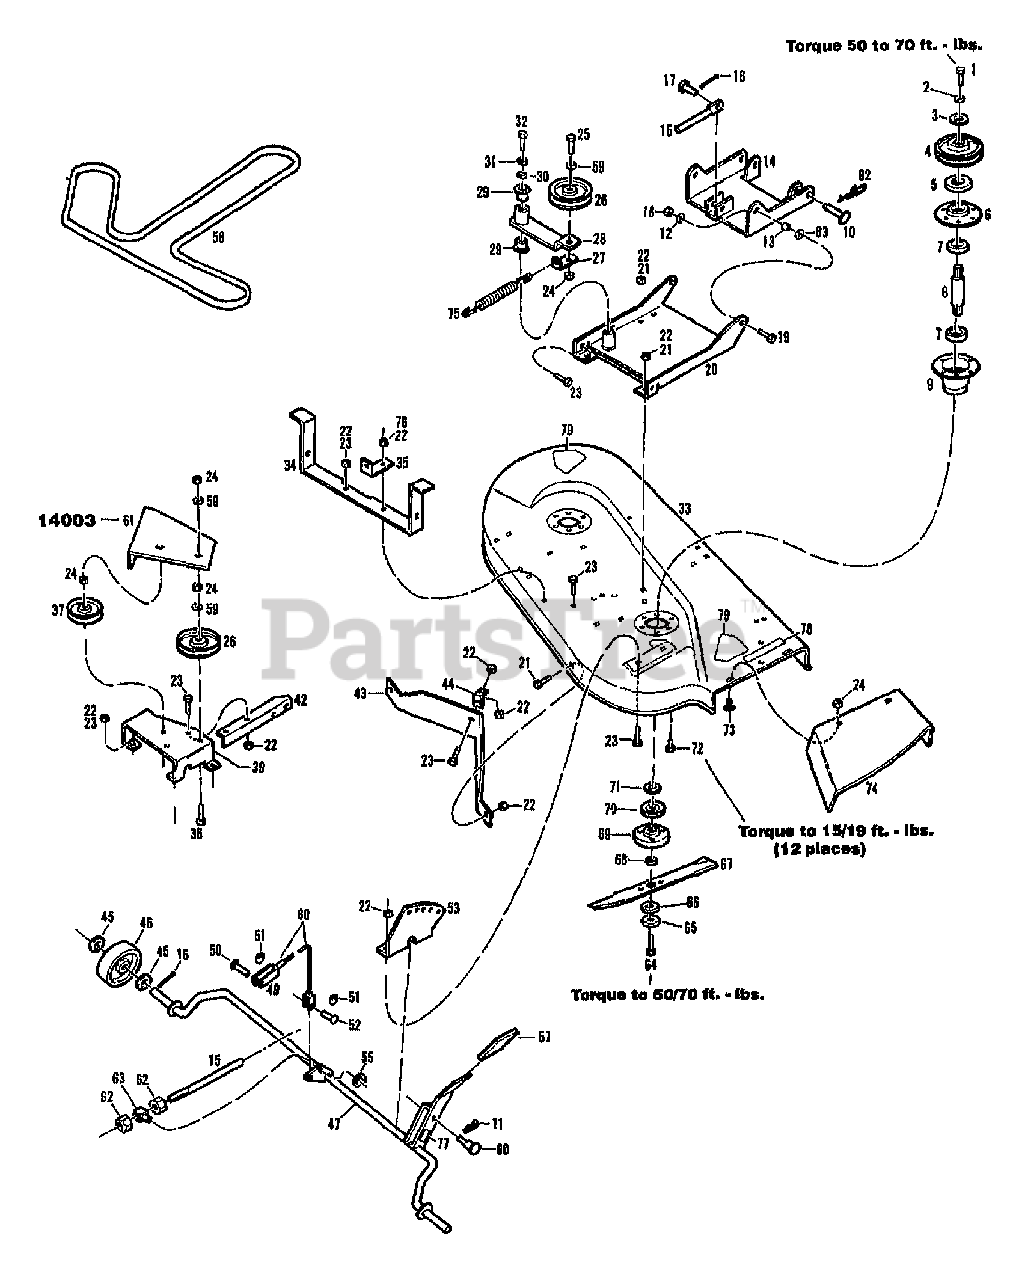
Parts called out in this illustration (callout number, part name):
1	SCR-HH 7/16-14X2.75 G5ZP
1	SCR-HH 7/16-14X3.0 G5 ZP
2	WASHER-LK .438 ZP
3	WASHER-1.37X.453X.179 ZP
4	ASSM-DRIVE SHEAVE
5	BEARING-UPPER SHIELD
6	HOUSING-ARBOR TOP
7	BEARING-BALL
8	SHAFT-ARBOR
9	HOUSING-ARBOR BOTTOM
10	PIN-CLEVIS .62X2.50 ZP
11	PIN-HITCH .125X2.56 ZP
12	WASHER-1/2 FLAT
13	SPACER-TUBULAR
14	ASSM-MOWER SUPT
15	ROD-ADJUSTOR
16	PIN-COTTER .120X1.25 ZP
17	PIN-CLEVIS .5X1.75 ZP
18	NUT-TOP LOCK 1/2-13 ZP
19	SCR-HH 1/2-13X1.25 G5 ZP
20	PLATE-MOWER SUPPORT
21	SCR-CARR 5/16-18X.75
22	NUT-TOP/LK 5/16-18 ZP
23	SCR-HHC 5/16-18X.75 GR 5 ZP
24	NUT-LOCK 3/8-16
25	SCR-HH 3/8-16X2.0 G5 ZP
27	GUIDE-BELT
28	ASSM-IDLER ARM
29	BEARING-FLANGE
30	WASHER-FLAT
31	WASHER-LK .375 @ DEPL
32	SCR-HH 3/8-16X.75 G5 ZP
33	ASSM-36" DECK W/DECALS
35	SPRING-ANCHOR
36	SCR-HH 3/8-16X2.25 G5 ZP
37	PULLEY-IDLER
39	SUPT-IDLER/AXLE
42	BRKT-SUPPORT
44	BRACKET-MOWER
45	WASHER-1.38 X.765X .06 ZP
46	GAUGE-WHEEL
47	ASSM-SUPT WHEEL SHAFT
49	YOKE
50	PIN-CLEVIS .5X1.437 ZP
51	RING-CIRCLE COTTER
52	PIN-CLEVIS .375 X .937 ZP
53	QUADRANT
55	RING-RETAINING EXT .694 ID
57	GRIP-HANDLE
59	WASHER-FLAT 3/8 SAE
61	GUARD-BELT {14003}
62	NUT-HEX
63	BLOCK-PIVOT
64	SCR-HH 1/2-14X1.00
65	WASHER-LK CONICAL .49 ID
66	WASHER-SPLINED
67	BLADE-MOWER
68	COLLAR-ARBOR
69	ADAPTER-BLADE
70	SHIELD-GRASS
71	WASHER-SHIM
72	SCR-HFLK 5/16-18X.75
73	SCR-CARR 3/8-16X.75 G5 ZP
74	DEFLECTOR-MOWER
75	SPRING-EXTENSION
76	SCR-HH 5/16-18X1.0 G5 ZP
77	DECAL-HEIGHT ADJUSTOR {14003}
78	DECAL-DANGER
79	DECAL-OPEI CAUTION
80	ASSM-CABLE(MOWER DECK)
82	RING-COTTER
83	WASHER
